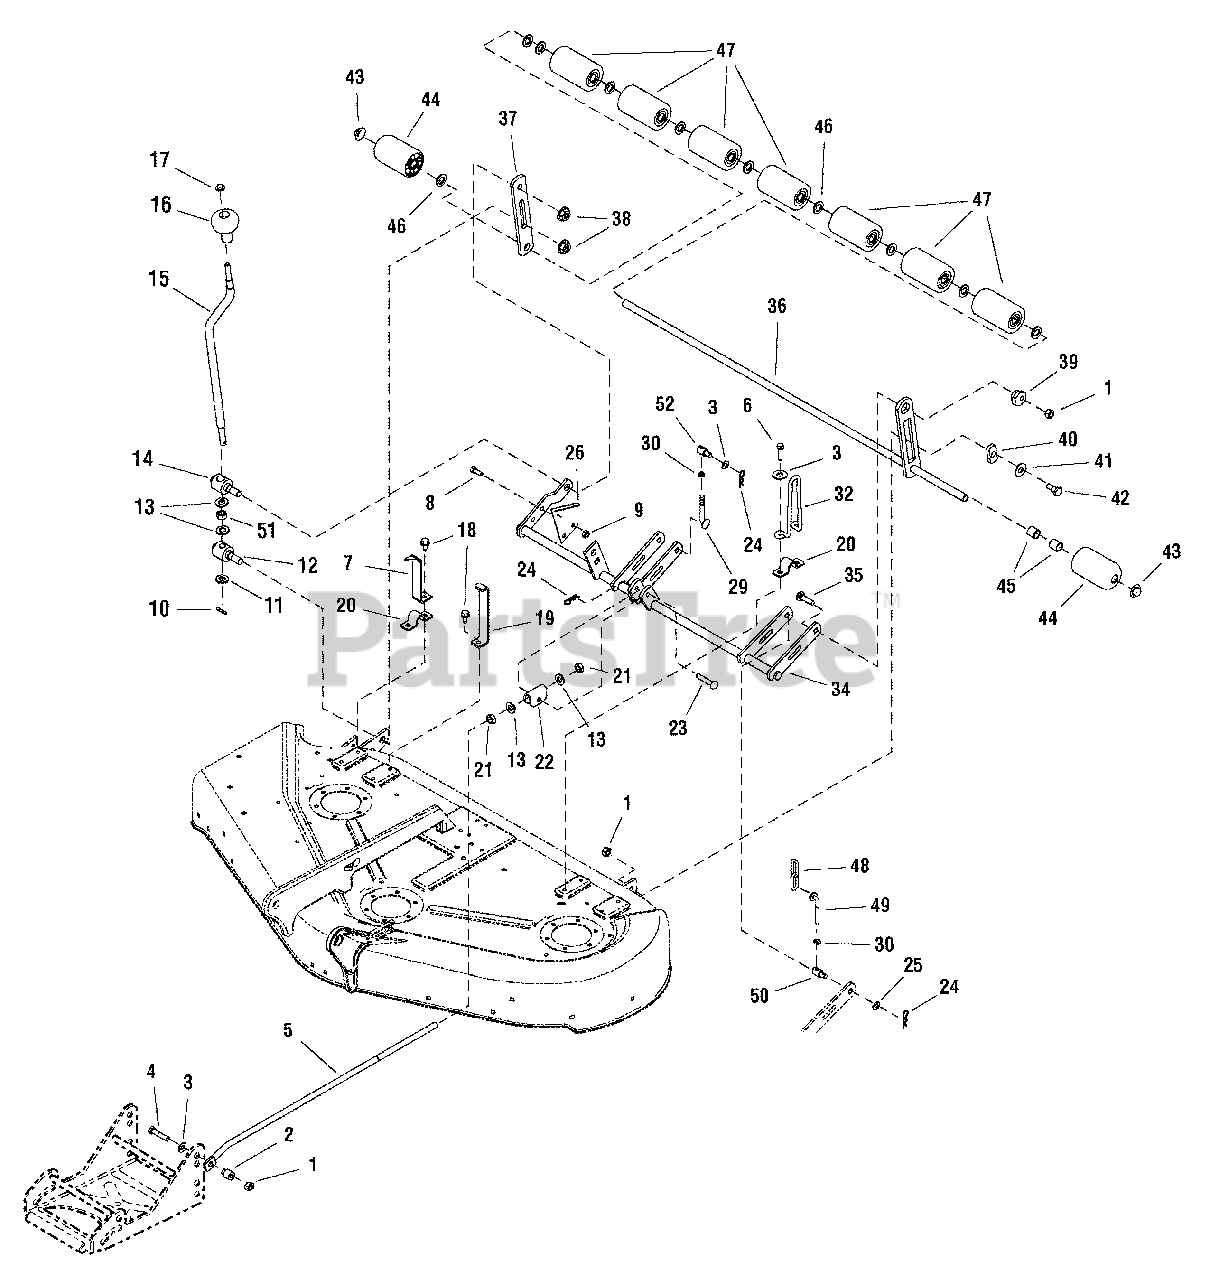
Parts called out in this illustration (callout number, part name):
1	NUT, Hex Toplock Spiral Lock Flange 3/8-16
2	SPACER, 3/8 x 3/4 x 15/16
3	WASHER, 3/8
4	CAPSCREW, Hex Head, 3/8-16 x 1-3/4
5	ROD, Adjustment
6	SCREW, Hex Washer Head Taptite 5/16-18 x 1-1/4
7	INDICATOR, Height of Cut
8	SCREW, Hex Whiz Lock Flange 5/16-18 x 3/4
9	NUT, Hex Flange 5/16-18 Whiz Lock Small
10	PIN, Spring
11	WASHER, Detent
13	WASHER, 1/2
15	CRANK, Height Adjust
16	KNOB, Spinner
17	NUT, Push Pal 3/8 Diameter Stud Capped
18	SCREW, Hex Washer Head Taptite 5/16-18 x 3/4
19	BRACKET, Up-Stop
20	STRAP, Roller
21	NUT, Hex Jam 1/2-13
22	TRUNNION, Rod
23	PIN, Round Head Drilled 3/8 x 2
24	CLIP, Hair Pin
25	WASHER, 3/8
26	BRACKET, Height of Cut
29	ROD,Height Adjuster
30	NUT, Hex Jam 5/16-18
32	UP-STOP, 6-14 High
34	SHAFT ASSEMBLY, Rocker 44"
35	CARRIAGE BOLT, 3/8-16 x 1-1/2 G5
36	SHAFT & BAR ASSEMBLY, 44"
37	BAR, Roller
38	NUT, Hex Flange 1/2-13 Two-Way Lock
39	NUT, Hex Adjusting, .99 DIA .687
41	WASHER, 1/2
42	BOLT, Shoulder, 3/8-16 X 1.34
43	NUT, Push for 5/8 Diameter Stud Capped
44	ROLLER, Rounded
45	SPACER, .66 ID
46	WASHER, 5/8
48	CHAIN, Link
49	ROD, Height Adjusting, 3/8-18
52	SWIVEL, Adjustable
